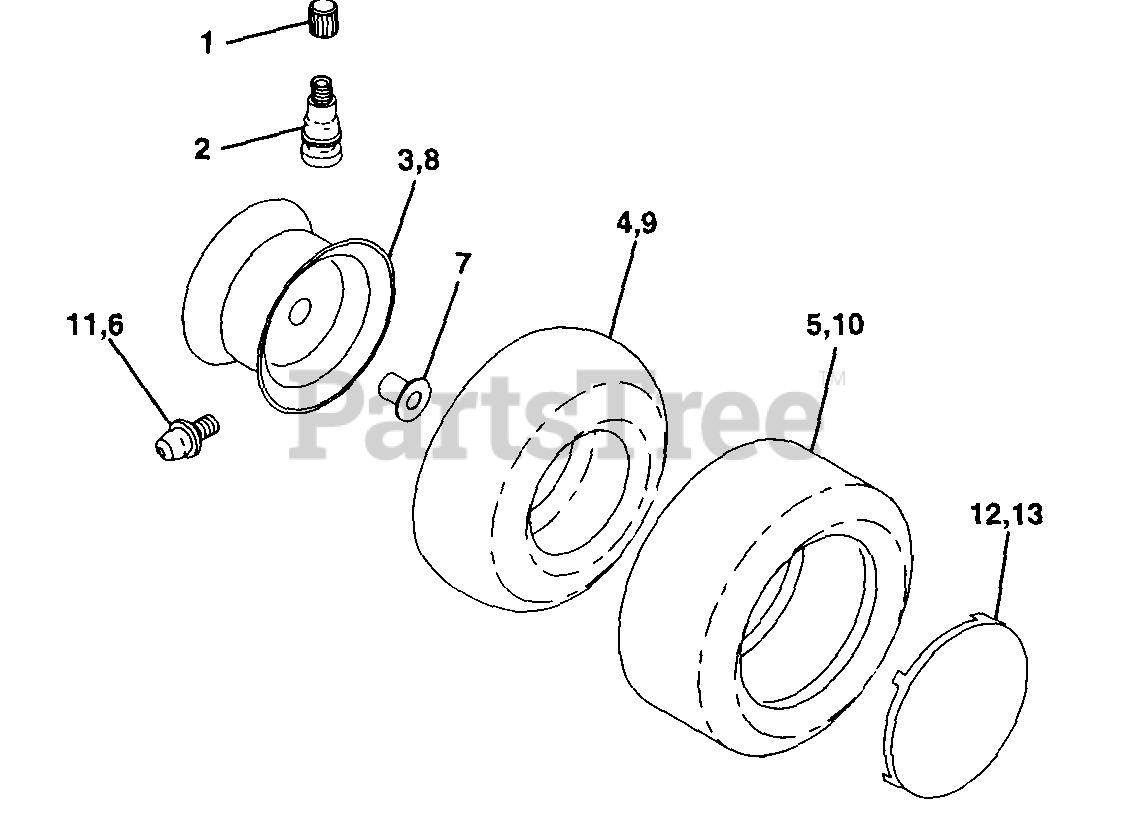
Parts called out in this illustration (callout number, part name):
1	Cap, Valve, Tire
2	Stem, Valve
3	Rim Assembly, Front
4	Tube, Front
5	Tire, Front
6	Fitting, Grease
7	Bearing, Flange (Front Wheel Only)
8	Rim Assembly, Rear
9	Tube, Rear
10	Tire, Rear
11	Fitting, Grease
12	Cover Wheel 8" White
13	Cover, Wheel 12" White
